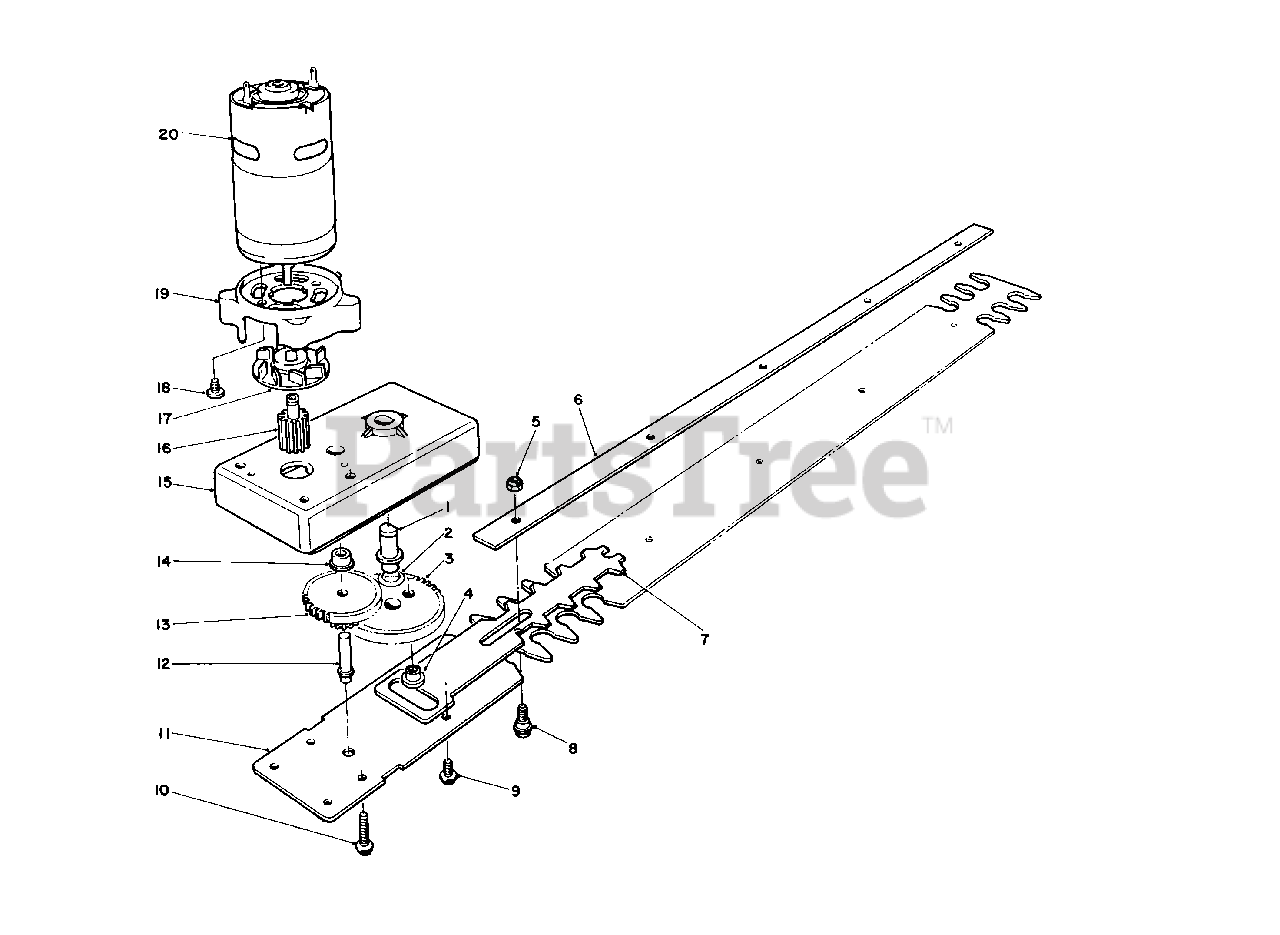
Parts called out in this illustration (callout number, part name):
1	Shaft-Driver
2	Washer-Wave
3	Gear-Drive
4	Bushing-Gear Drive
5	Nut-Lock
6	Retainer-Blade
7	Blade-Cutting
8	Bolt-Blade
9	Screw-Hex Washer Hd.
10	Screw-Hex Washer Hd.
11	Blade-Bottom
12	Shaft-Idler
13	Gear-Idler
14	Bearing-Idler
15	Housing-Gear Ass'y (Incl. Ref. #1 & 14)
16	Gear-Motor
17	Fan-Motor
18	Screw-Phillips Hd. Pan
19	Support-Motor
20	Motor Assembly (Incl. Ref. #16-19)
